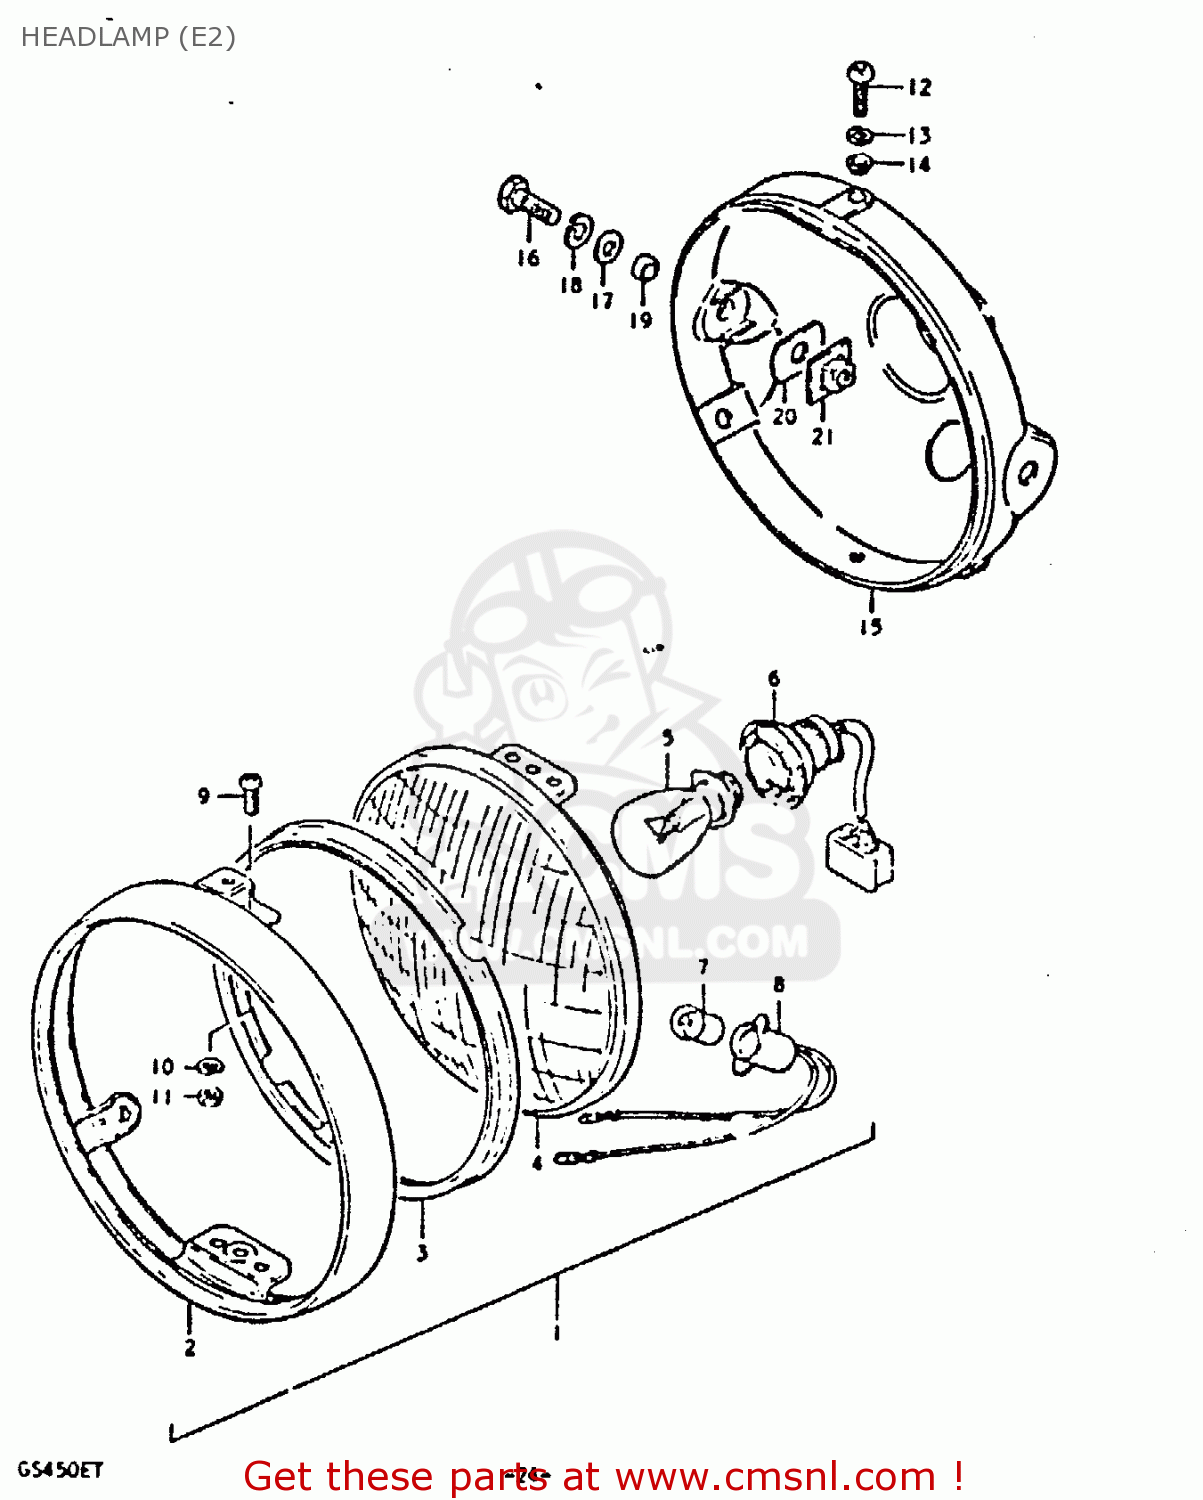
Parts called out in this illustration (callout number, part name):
1	HEADLAMP ASSY
2	RIM
3	RETAINER,HEADLAMP
4	UNIT, HEAD LIGHT
5	BULB 12V35/35W
6	SOCKET
7	BULB(12V3.4W,STANLEY,A72A)
8	SOCKET
9	SCREW
10	LOCK WASHER
11	NUT
12	SCREW
13	WASHER,LOCK
14	WASHER
15	HOUSING,HEADLAMP(BLACK)
16	BOLT
17	WASHER
18	LOCK WASHER
19	SPACER (8.8X12X7)
20	CUSHION
21	PLATE,HEADLAMP HOUSING
